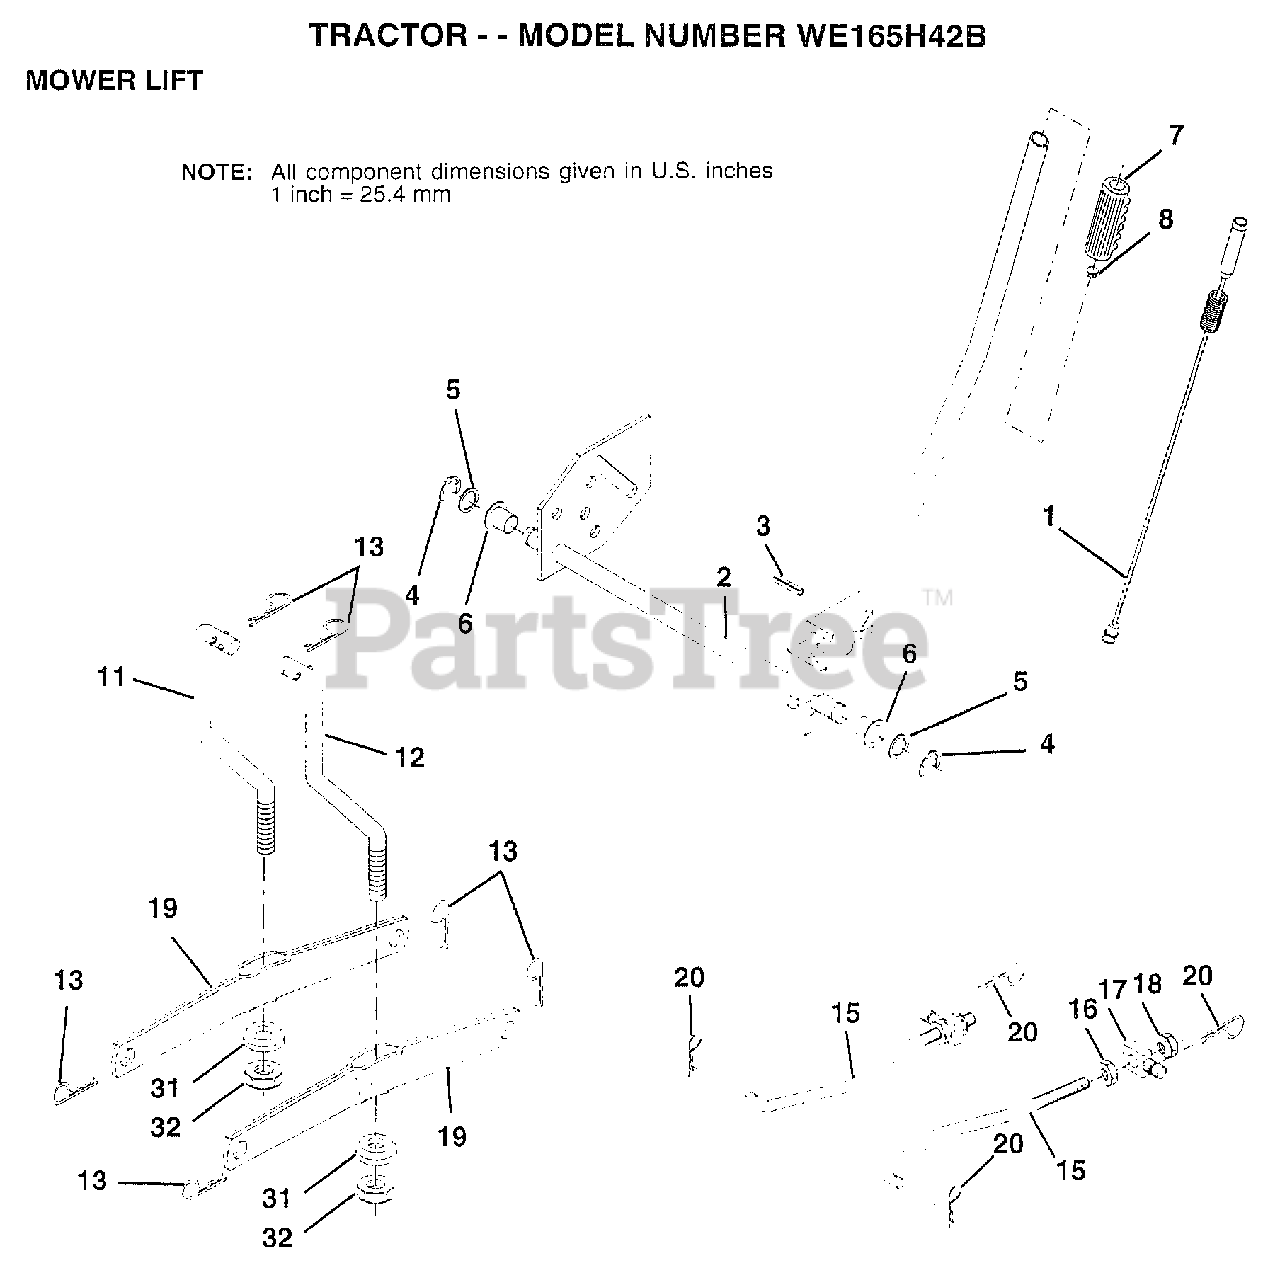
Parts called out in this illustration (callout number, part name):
1	WIRE ASM W.SPRING
2	"SHAFT ASM LIFT,RH"
3	PIN-GROOVE LT
5	WASHER
6	NYLON BEARING
7	GRIP
15	LINK.FRONT
16	NUT
17	TRUNION
18	NUT LTV
19	ARM SUSP REAR
20	RETAINER SPRING
31	BEARING PVT LH
32	NUT.CROWNLOCK.3/8
